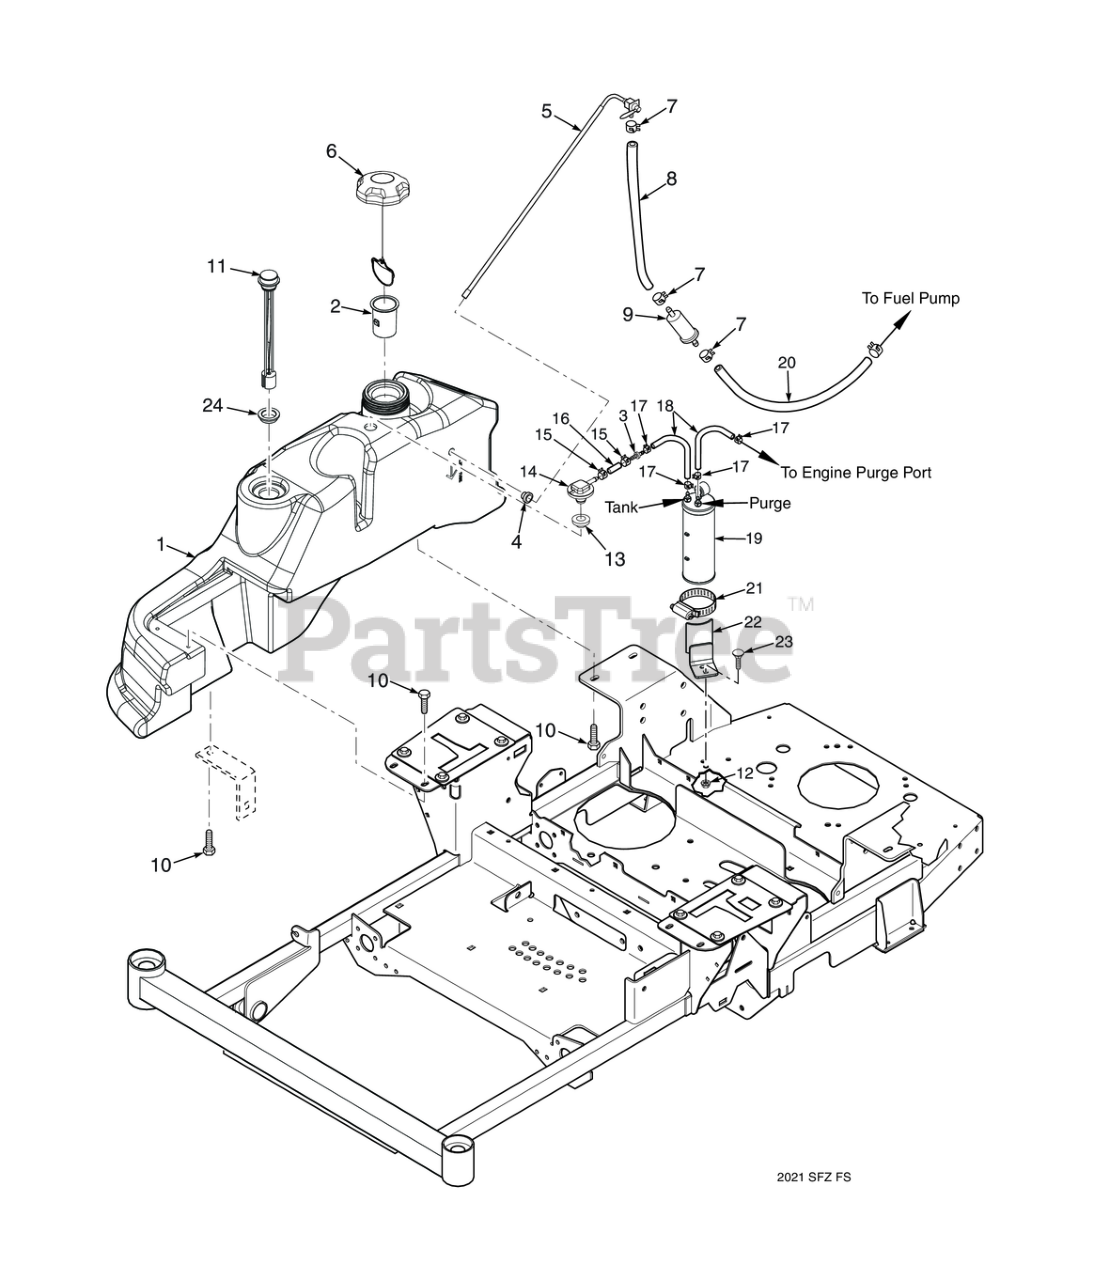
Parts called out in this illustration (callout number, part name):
1	Fuel Tank Assembly
2	Tube, Fuel Tank Insert - 4"
3	Mender, 1/4 x 3/16 w/0.02 Hole
4	Bushing, 0.56" Dia. Viton
5	Fuel Tube Assembly
6	Fuel Cap w/ Tether (E.P.A.)
7	Clamp, Fuel Hose 1/4" Hose I.D.
8	Fuel Hose, 1/4" I.D. Non-Perm (791DFI Fuel Return) - Order by Inch
9	Fuel Filter
10	Capscrew, 5/16-18 x .75 Serrated Flange Hex Head
11	Fuel Gauge Assembly
12	Nut, Serrated Flange 5/16-18 (Right Front Engine Mounting, Briggs and Kohler Only)
13	Grommet, Viton,
14	Remote Vent, No Valve
15	CLAMP, FUEL HOSE(KAWASAKI ONLY)
16	Hose, 1/4" Vapor Recovery (order by inch)
17	Clamp, Vapor Recovery Hose 3/16"
18	Hose, Vapor Recovery 3/16" (order by inch)
19	Carbon Canister - SVR-52V / SVR-61V
20	Fuel Hose
21	Clamp, 3-1/2" Max. Dia.
22	Bracket Weldment, Kohler Models
23	Bolt, 5/16-18 x .75 RHSN Carriage
24	Grommet, Fuel Gauge
